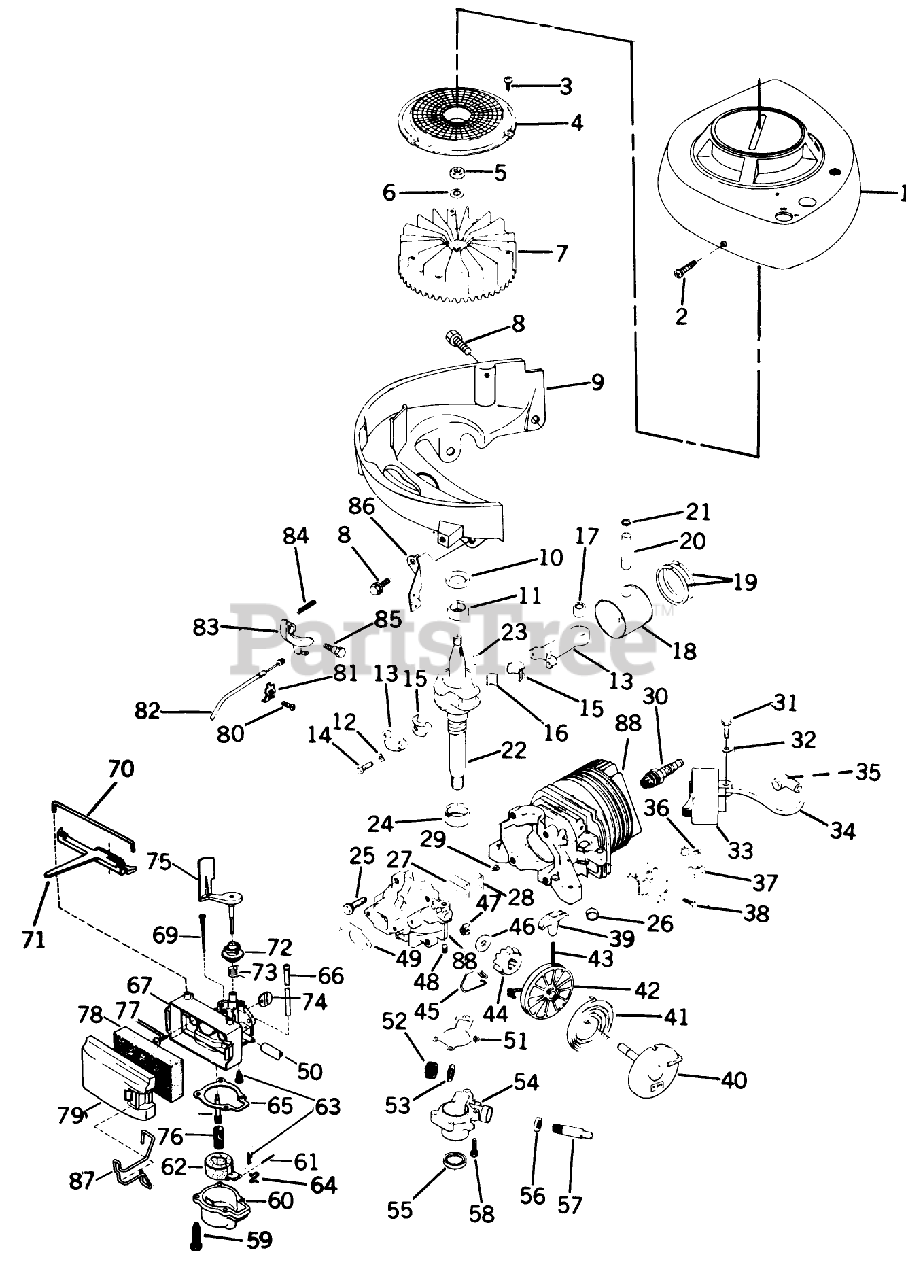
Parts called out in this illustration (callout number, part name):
2	SCREW F
3	SCREW F
5	NUT
8	SCREW-SEMS
11	BEARING V
14	SCREW
15	LINER ASM
17	BEARING AY F
21	RING-RETAINING
23	KEY
24	BEARING S
25	SCREW S
26	PLUG-CORE VF
28	PLATE-BACKUP, REED
32	TERMINAL S
34	HT LEAD&COVER XEV
36	NUT-CLIP
37	BRACKET S
39	HANDLE STARTER S
41	SPRING S
45	SPRING F
46	WASHER S
49	GASKET CARB S
51	GASKET S
52	GEAR, DR SHAFT S
53	Washer-Thrust
56	SEAL S
59	SCREW-HH
66	TUBING PRIMER S
68	NEEDLE ADJ. AY S
69	NEEDLE ADJ. AY S
70	RETAINER
71	LEVER S
72	COLLAR-ADJUST, AIRVANE
73	SPRING,THROTTLE S
74	DISC S
75	AIR VANE&SHAFT S
76	FILTER-FUEL VS
77	SCREW
81	CLIP S
83	LEVER LOCKOUT S
85	BOLT S
87	RETAINER-COVER, FILTER
